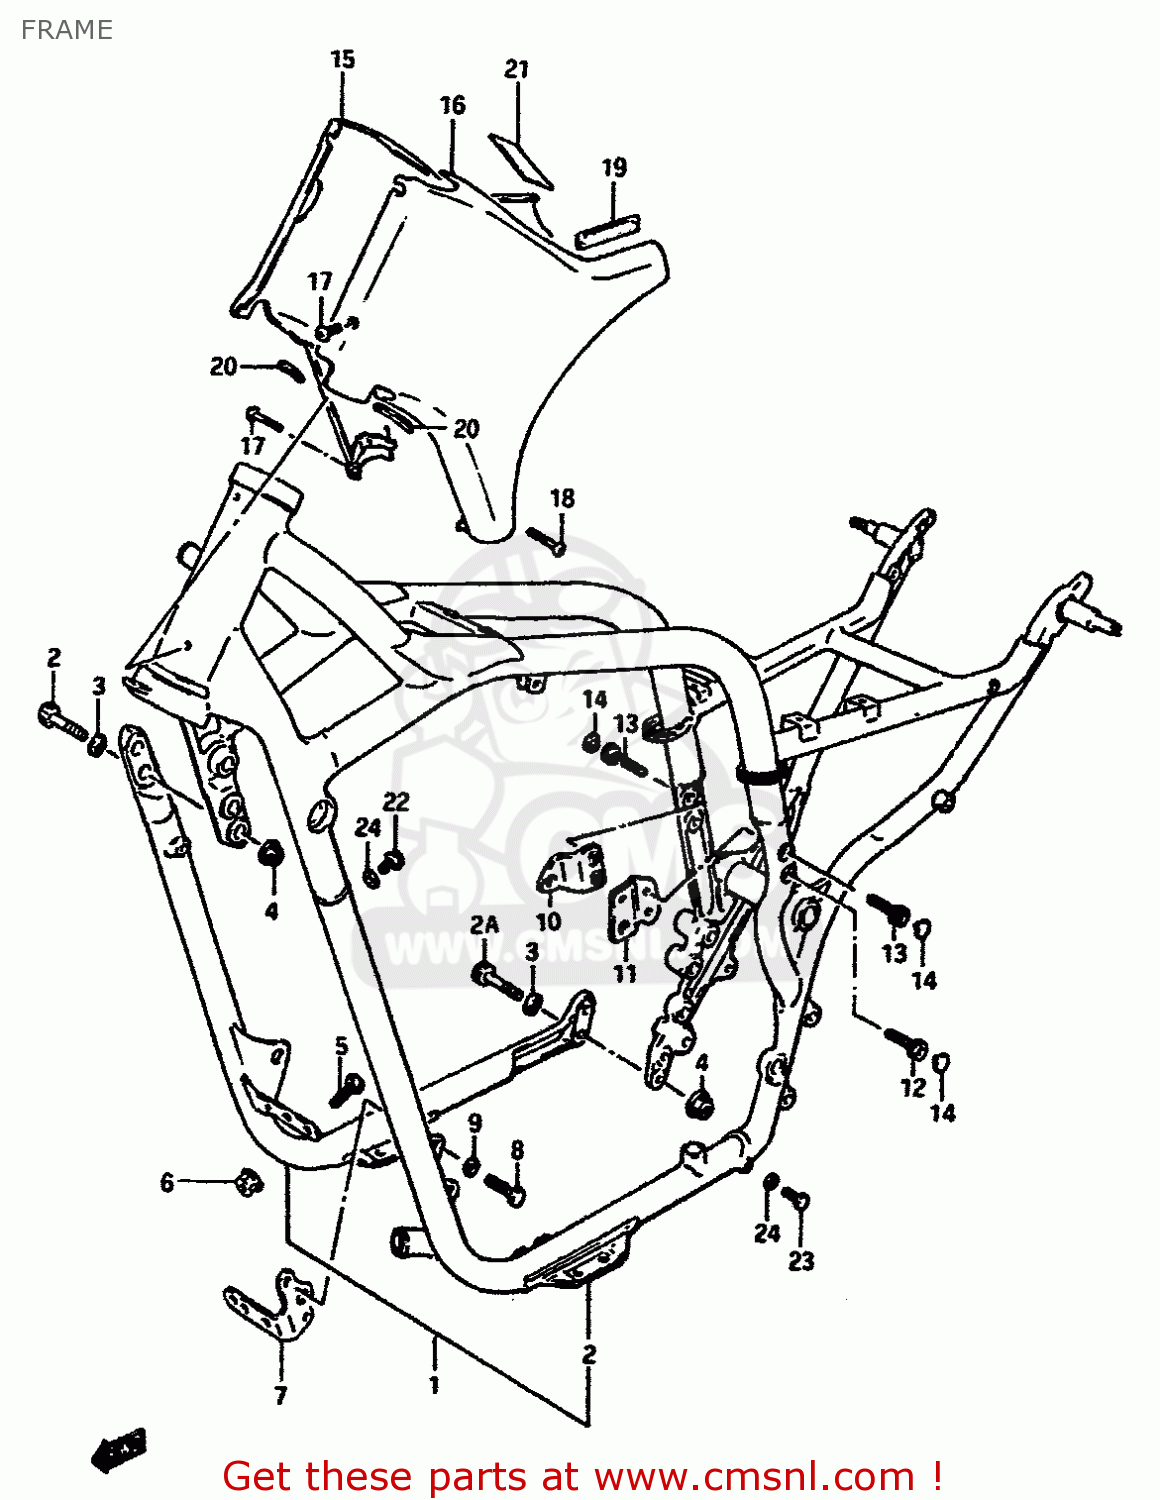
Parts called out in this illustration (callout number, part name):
1	FRAME SET (MAROON)
2	TUBE,FRAME
2A	BOLT(10X33)
3	WASHER
4	NUT 10MM
5	BOLT
6	NUT
7	PLATE,ENGINE MOUNTING
8	BOLT
9	WASHER,LOCK,8.
10	PLATE,ENGINE MOUNTING
11	PLATE,ENGINE MOUNTING
12	BOLT 8X30
13	BOLT(8X30)
14	CAP(OD:14.5)
15	COVER,FRAME HEAD,RIGHT
16	COVER,FRAME HEAD,LEFT
17	SCREW 5X10
18	SCREW
19	PROTECTOR(20X90)X2
20	MOLDING,FUEL TANK
21	TAPE,FRAME HEAD COVER
22	UNION
23	BOLT
24	GASKET(6.2X11X1).2 (NAS)
